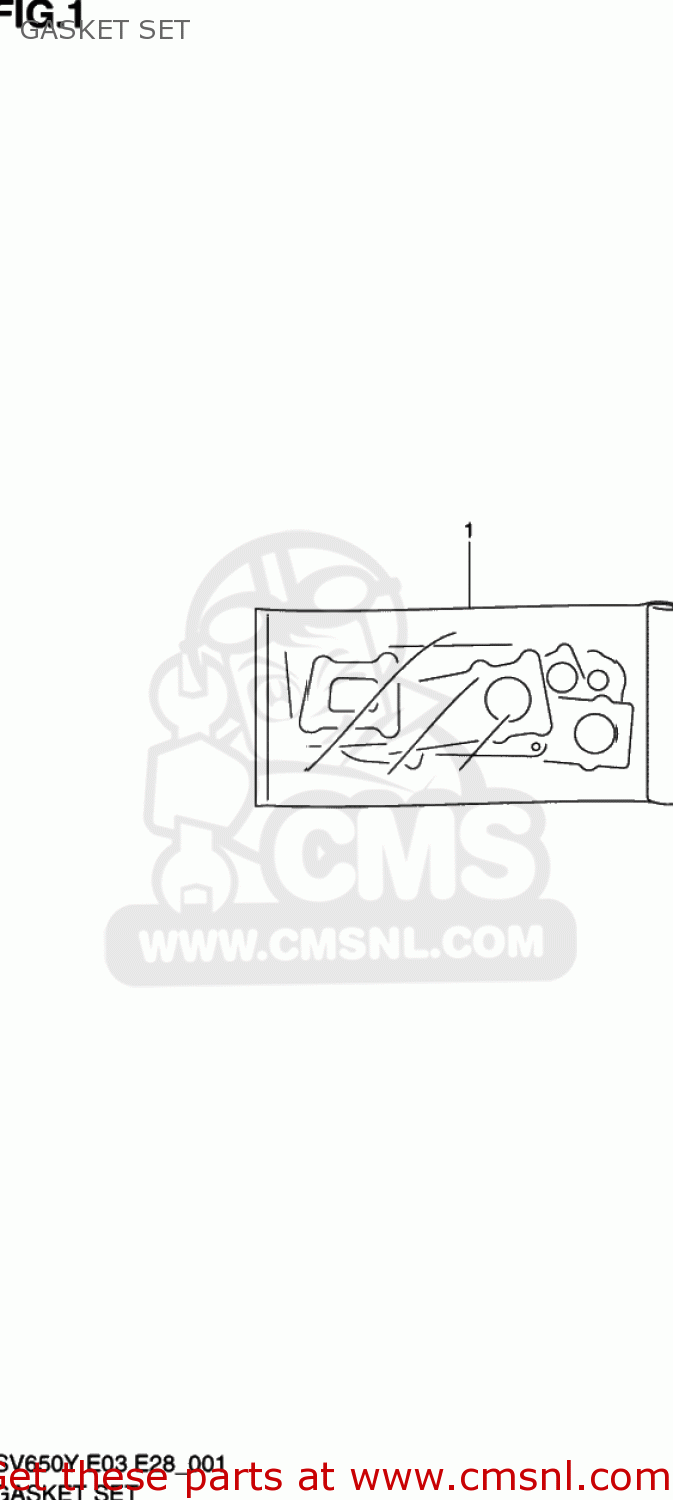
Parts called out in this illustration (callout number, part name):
1	GASKET SET (NAS)
2	GASKET,CYLINDER HEAD (NAS)
3	GASKET,CYLINDER HEAD COVER (NAS)
4	GASKET,CYLINDER FR (NAS)
5	GASKET,CYLINDER RR (NAS)
6	GASKET,CLUTCH COVER INNER (NAS)
7	GASKET,MAGNETO COVER (NAS)
8	O-RING,CLUTCH COVER,OUTER
9	GASKET,TENSIONER ADJUSTER (NAS)
10	GASKET,EXHAUST PIPE (NAS)
11	WASHER(10.6X25.5X2.3)
12	O RING(D:3.1,ID:22.7)
13	O RING(D:2.4,ID:47X42)
